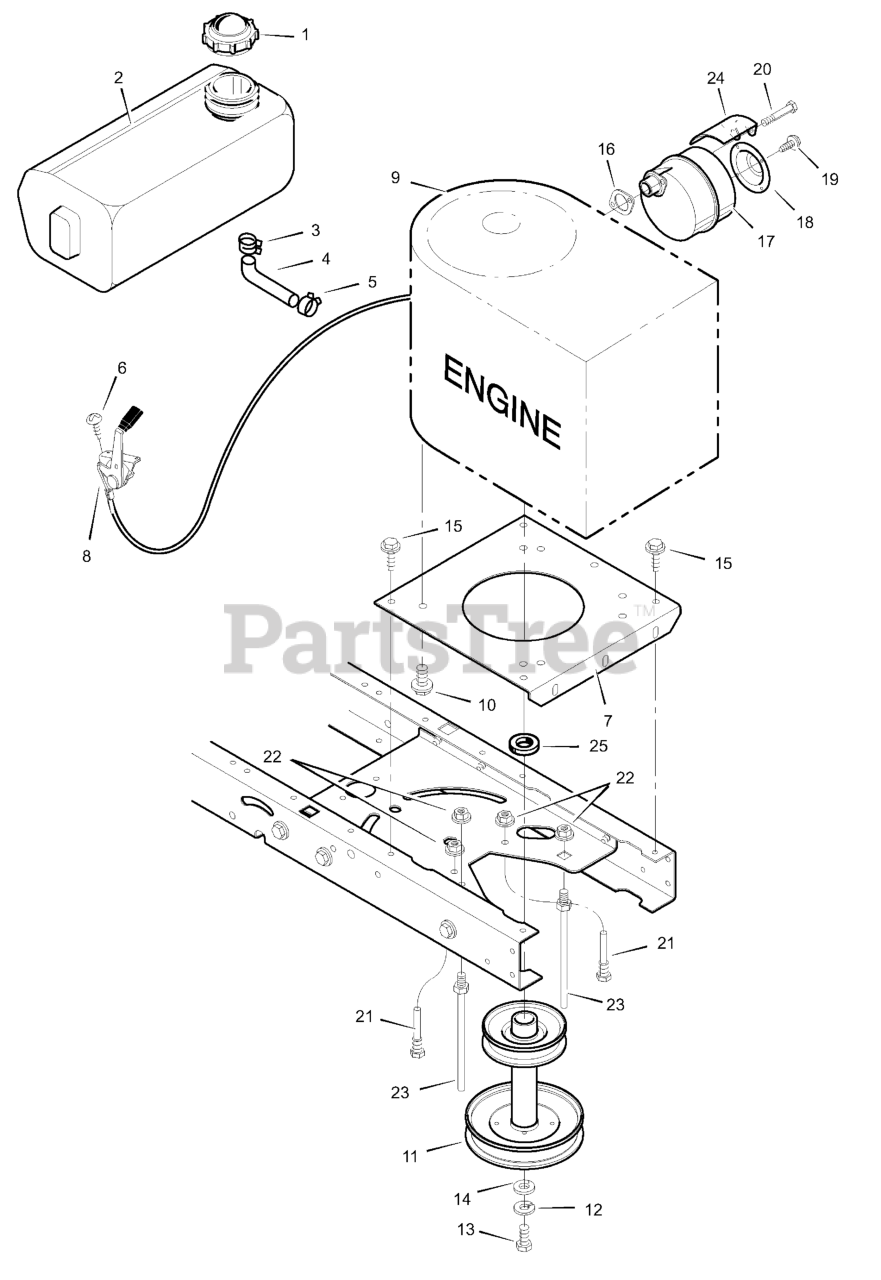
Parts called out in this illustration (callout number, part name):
1	Fuel Cap
2	Fuel Tank
3	Hose Clamp
4	Fuel Line
5	Hose Clamp
7	Plate, Engine
8	Throttle Control
9	Engine
10	Bolt, Engine Mount
11	STACK PULLEY ASSEMBLY
12	Lockwasher
13	Bolt, Hex
16	GASKET, Exhaust
17	Muffler
18	Deflector, Muffler
20	Bolt, Hex
21	Guide, Belt
22	Nut, Flange
23	Guide, Belt
24	Shield, Heat
